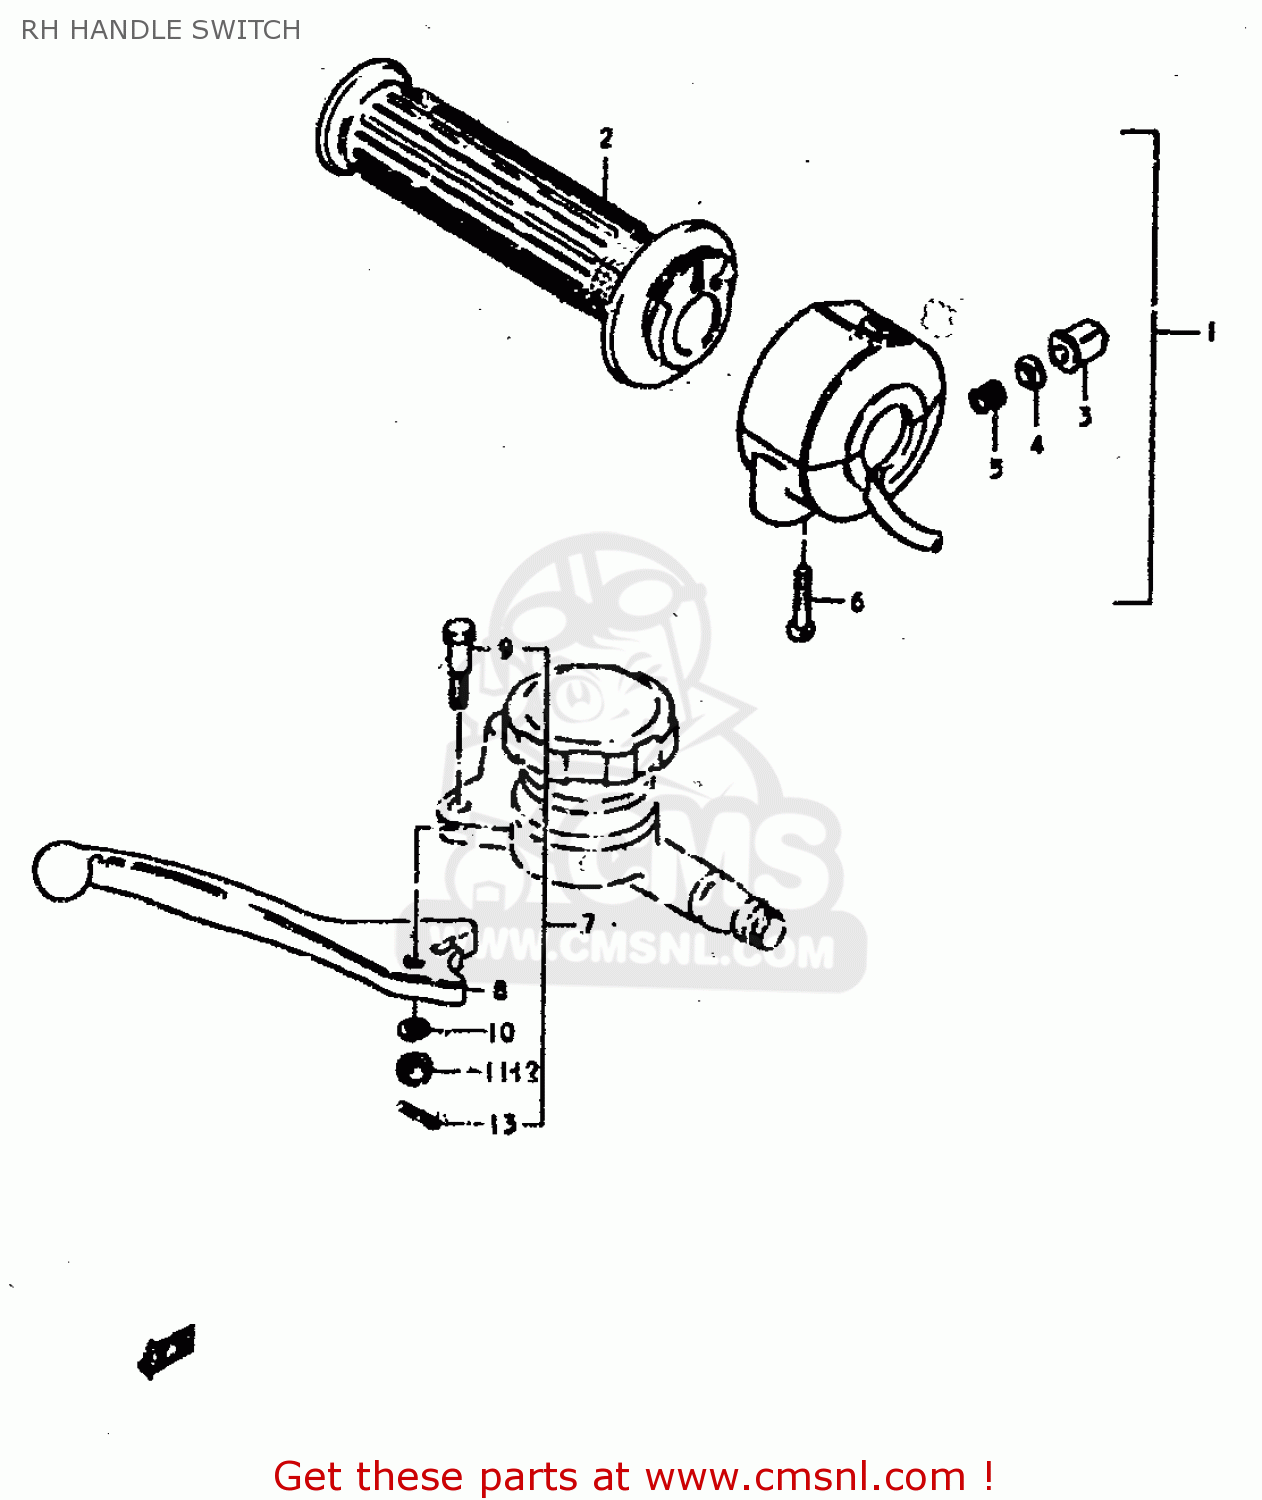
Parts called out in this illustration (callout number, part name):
1	CASE ASSEMBLY,THROTTLE
2	GRIP,THROTTLE
3	BUTTON,HORN
4	CONTACT
5	SPRING
6	SCREW
7	LEVER ASSEMBLY,BRAKE
8	LEVER,BRAKE
9	BOLT,LEVER
12	NUT 6MM
